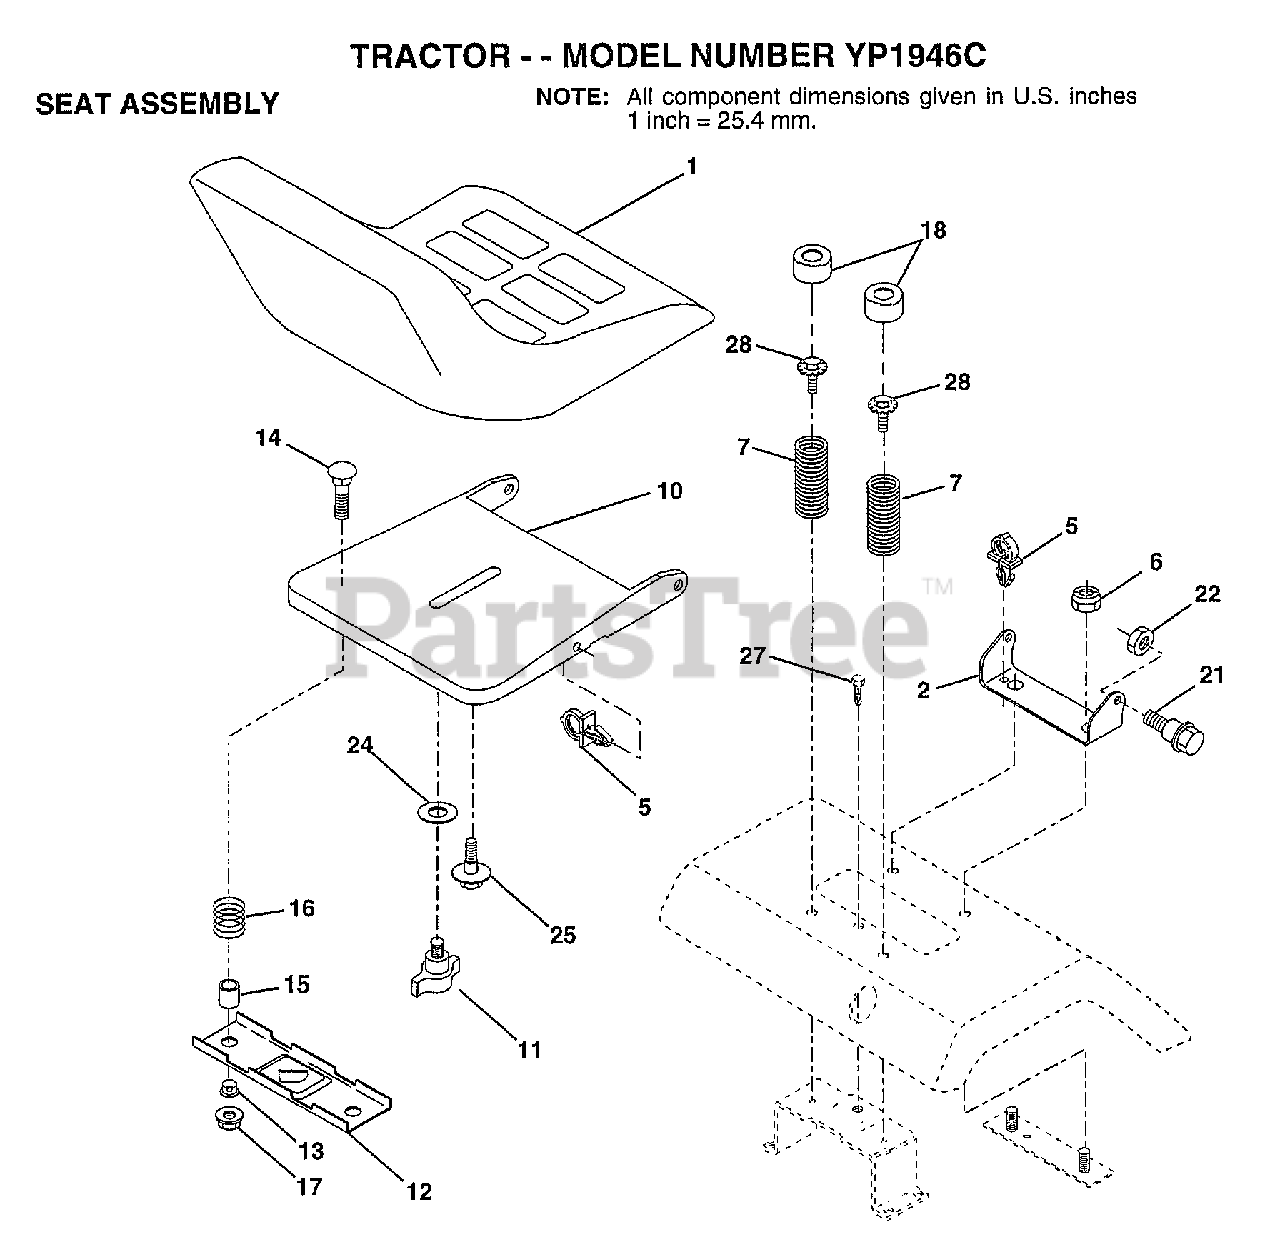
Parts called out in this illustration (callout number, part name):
1	SEAT.2500/1516.BK
2	BRACKET PVT SEAT
5	CLIP.PUSH-IN.HING
6	NUT
7	SPRING COMPRESSIO
10	PAN-SEAT
11	KNOB.SEAT.ADJ.WINGNUT
12	BRKT SWITCH
13	BUSHING
14	BOLT-RD HD SQ NK
15	SPACER SPLIT
16	SPRING COMPRESSED
18	CAP SPRING
21	"BOLT,SHOULDER"
22	NUT
24	WASHER
25	"BOLT,SHOULDER"
27	SCREW LT
28	BOLT.5/16-18.UNC
